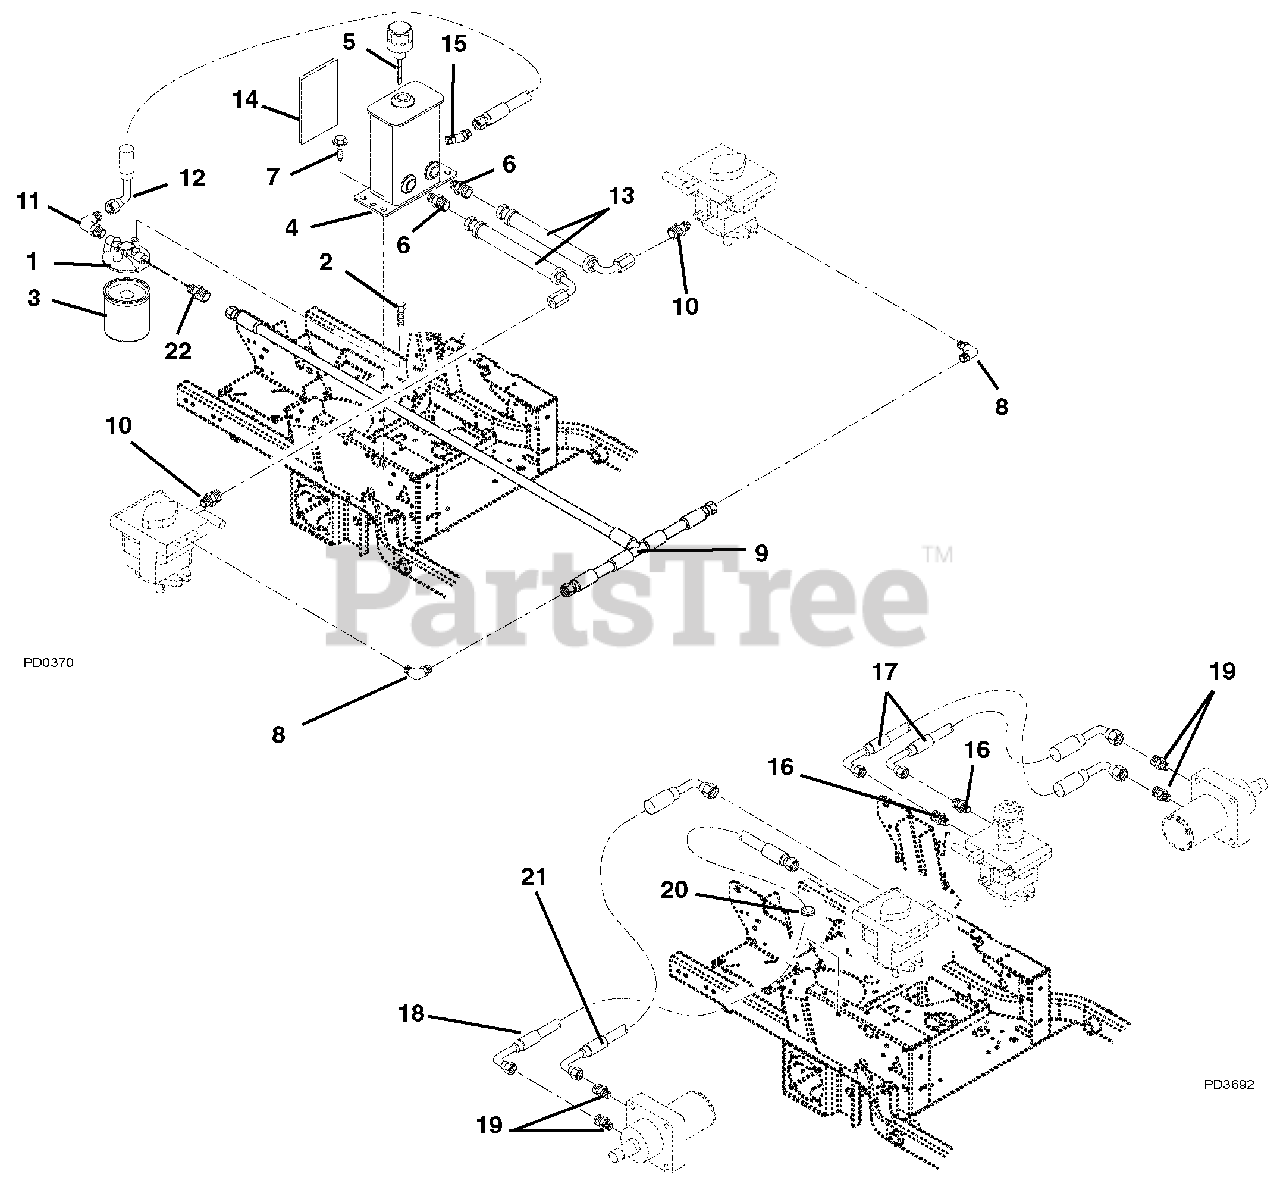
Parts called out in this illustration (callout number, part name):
1	Head, Filter (Serial Numbers 000500 and Up)
2	Bolt, Hex .25-20 x .50 Grade 5 Epoxy
3	Oil Filter (Serial Numbers 000500 and Up)
4	Tank, Hydraulic (Serial Numbers 007500 and up)
5	Hydraulic Tank Dipstick
6	Fitting, Hydraulic Straight M8O-M4F
7	Screw, Tapping .38-16 x .75 Hex Washer Head
8	Fitting, Hydraulic
9	Hose, Hydraulic (Serial Numbers 000500 and Up)
10	Fitting, Hydraulic
11	Fitting, Hydraulic 90 Degree Elbow (Serial Numbers 000500 and Up)
12	Hose, Hydraulic .50-11-OK F8FO-F8F9 (Serial Numbers 7500 and up)
13	Hose, Hydraulic
14	Shield, Heat 5.50 x 4.50
15	Adapter, Face Seal 8x8 .50 O-Ring 8F5OLO - Steel (Serial Numbers 007500 and up)
16	Adapter, Hydraulic
17	Hose, Hydraulic
18	Hose, Hydraulic
19	Adapter, Hydraulic (991026, 027, 028, 031)
20	Grommet, 1.25
21	Hose, Hydraulic
22	Adapter 8 x 8 Face Seal (Serial Numbers 000500 and Up)
